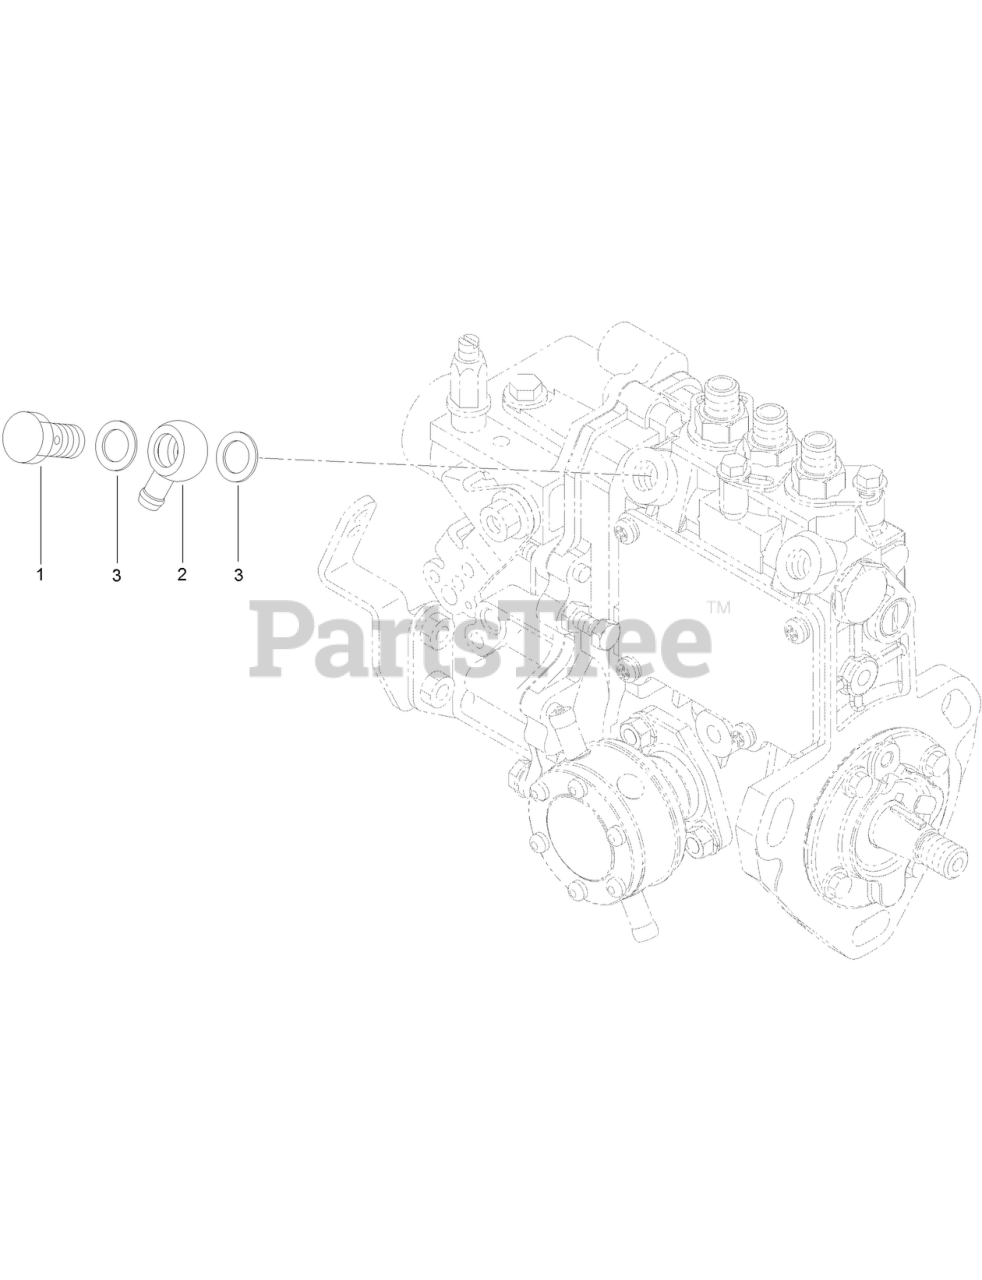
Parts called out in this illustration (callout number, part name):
1	BOLT-PIPE JOINT
2	JOINT-PIPE
3	WASHER-SEAL
